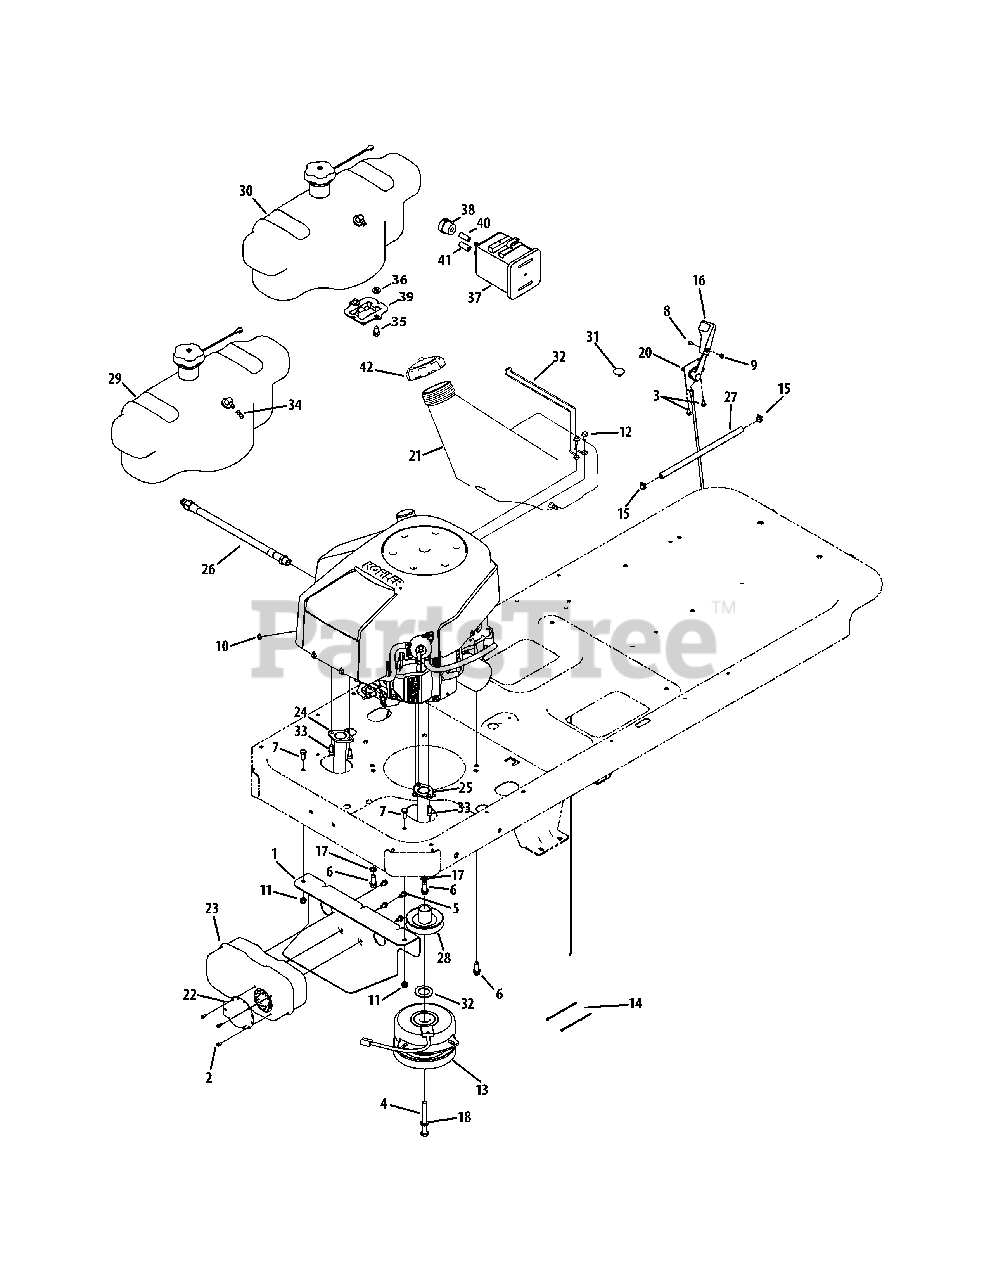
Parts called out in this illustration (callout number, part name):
1	Muffler Mount Bracket
2	Hex Washer Screw, #8-18 x .500
3	Screw, 1/4-14 x .625
4	Hex Screw, 7/16-20 x 3.25
5	Hex Washer Screw, 1/4-20 x .500
6	Hex Washer Screw, 3/8-16 x 1.000
7	Hex Washer Screw, 5/16-18 x .75
8	Machine Screw, #8-32 x .375
9	Hex Nut, #8-32
10	Sems Nut, 1/4-20
11	Flange Lock Nut, 5/16-18
12	Hex Washer Screw, 5/16-18 x .750
13	Electric PTO Clutch
14	Cable Tie
15	Hose Clamp
16	Throttle Control Knob
17	Lock Washer, 3/8
18	Lock Washer, 7/16
20	Throttle/Choke Control Cable
22	Muffler Deflector
23	Dual Inlet Muffler
24	Exhaust Pipe, LH
25	Exhaust Pipe, RH
26	Oil Drain Hose
28	Engine Pulley
29	Fuel Tank Assembly
30	Fuel Tank Assembly
30	Fuel Tank Bushing
30	Rubber Grommet
30	Fuel Pick-Up Fitting
30	Fuel Cap
30	Rollover Valve
31	Choke Plug
32	Flat Washer, 1.03 x 1.620 x .095
33	Screw, 5/16-18 x .750
34	Hose Vent, 3/16 EPA
35	Screw 5/16-18 x .875
36	Washer, Flat, .344 x .750 x .120
37	Canister, Carbon, 5 Gallon
38	Filter, Vent, Canister
39	Bracket., Adapter, Canister
40	Hose, Fuel, Low Perm., White
41	Hose, Fuel, Low Perm., Yellow
